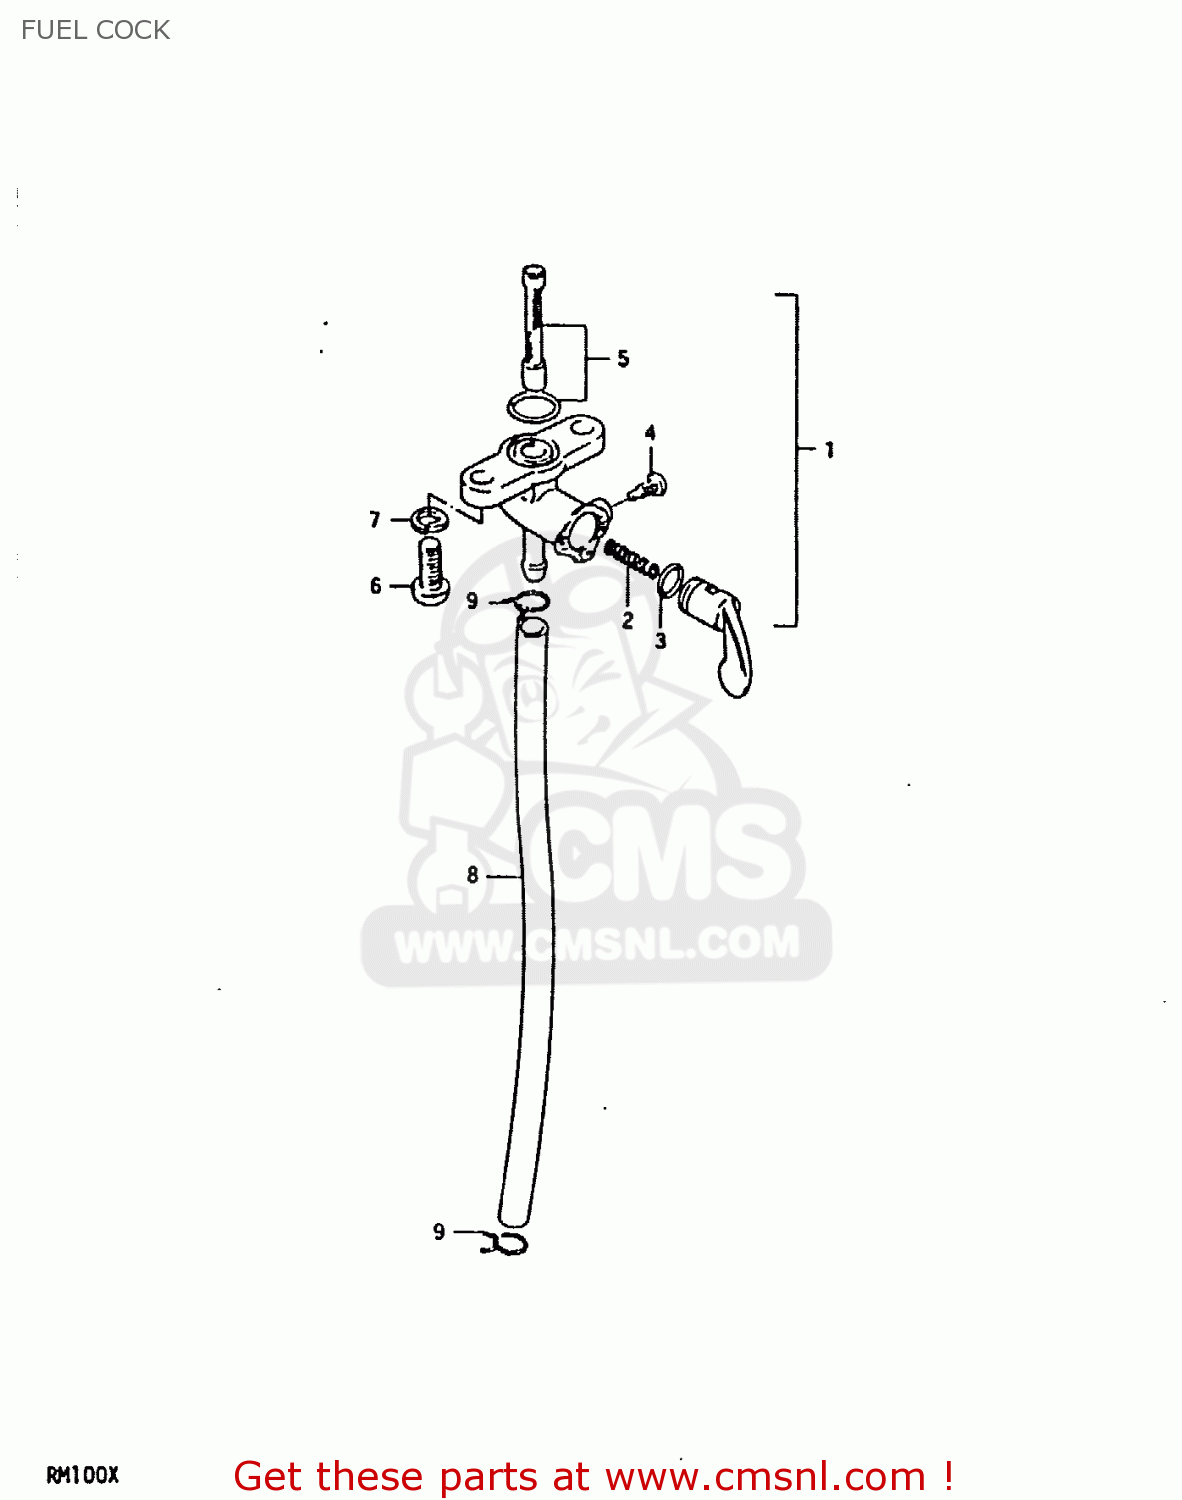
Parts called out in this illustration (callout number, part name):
1	COCK ASSEMBLY,FUEL
2	SPRING,FUEL COCK VALUE
3	O RING,LEVER
4	SCREW
5	FILTER SET FUEL
6	SCREW
7	LOCK WASHER
8	HOSE
9	CLIP
